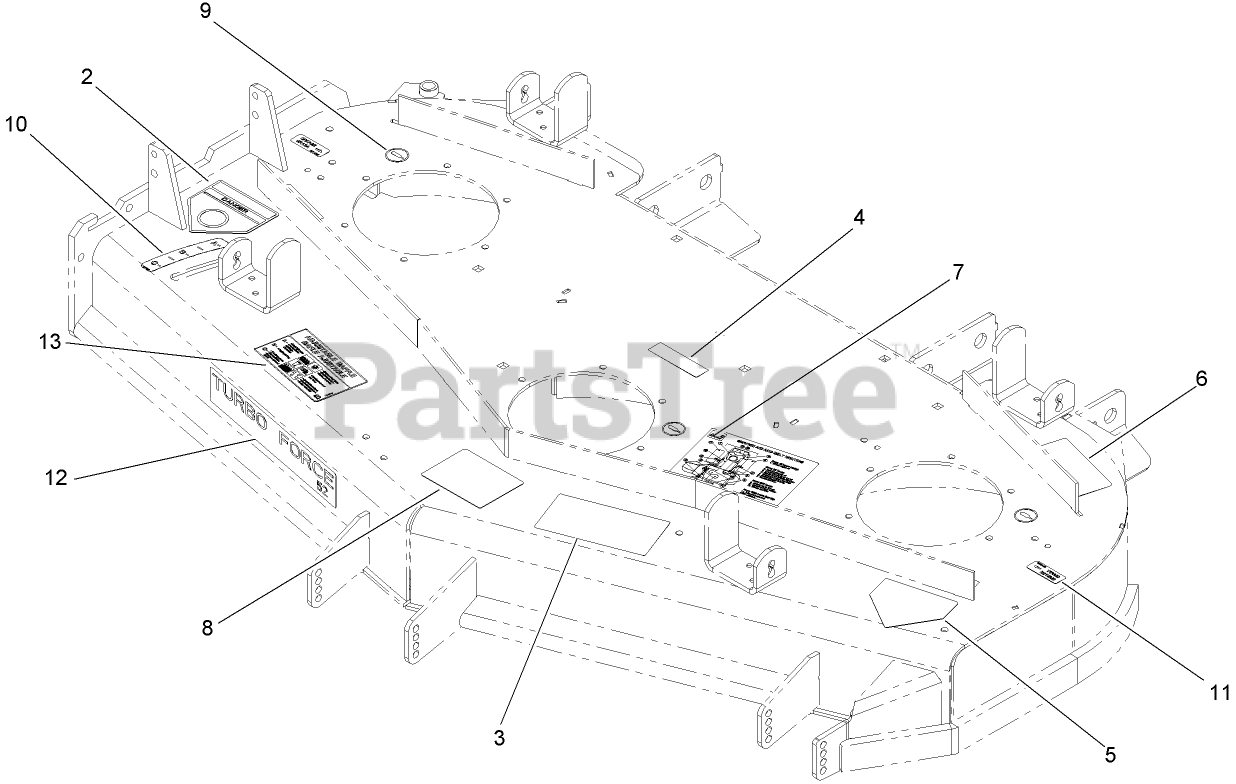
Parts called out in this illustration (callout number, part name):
2	DECAL-DANGER
3	DECAL-DANGER, THROWN OBJECT
4	DECAL-COVER, MISSING
5	DECAL-DANGER
6	DECAL-TORQUE
7	DECAL-AID, SERVICE
8	DECAL-SCALP, ANTI
9	DECAL-GREASE
10	DECAL-SETTING, BAFFLE
11	Decal-Grease
13	DECAL-ADJUSTMENT, BAFFLE
